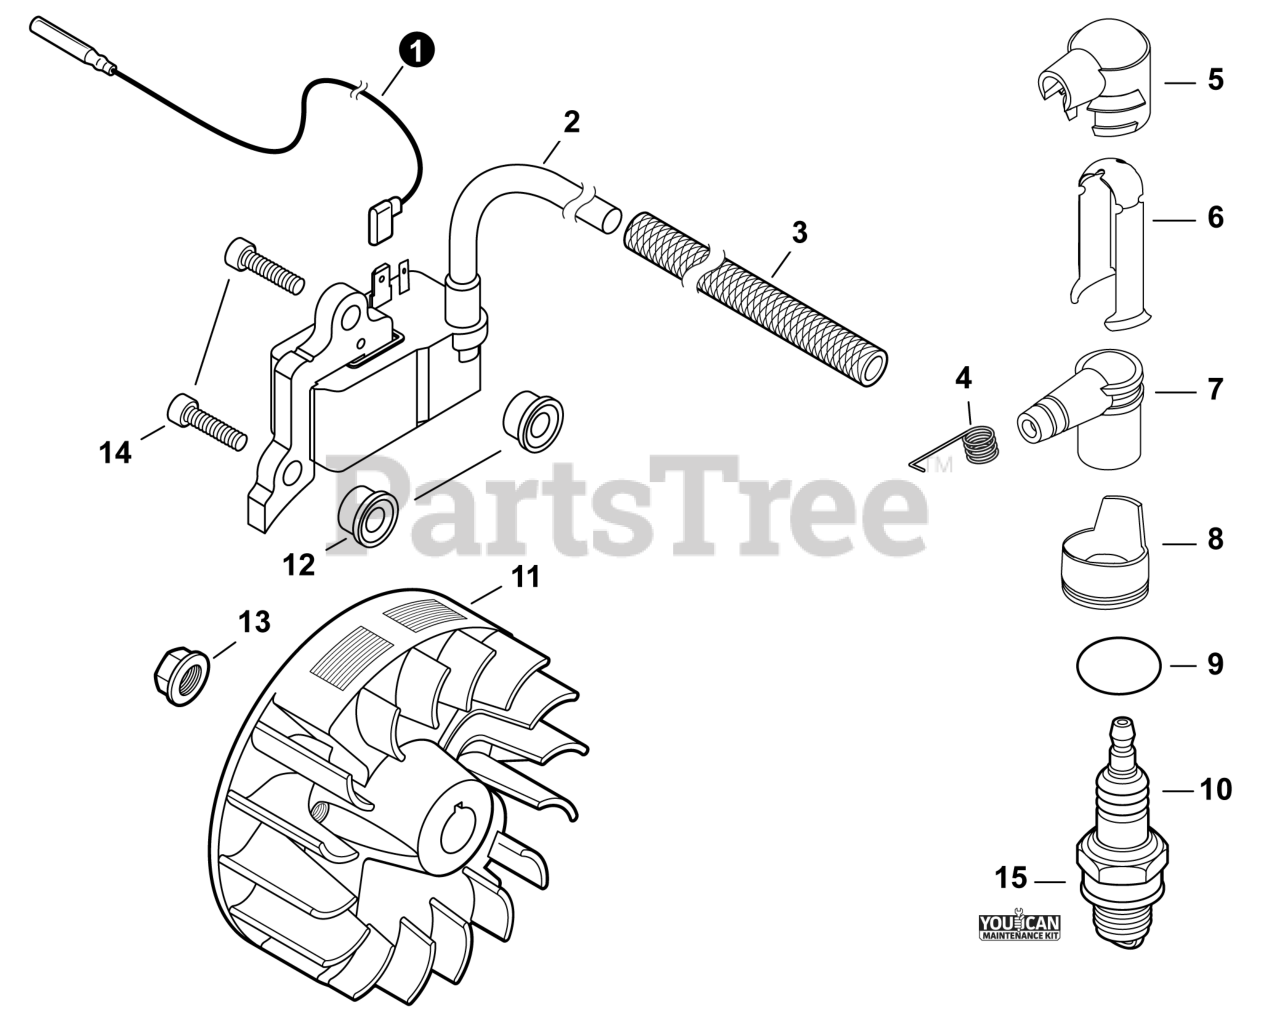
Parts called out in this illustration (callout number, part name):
2	COIL, IGNITION
3	TUBE, INSULATOR
4	TERMINAL, SPARK PLUG
5	COVER, CAP
6	SHIELD, SPARK PLUG
7	CAP, SPARK PLUG
8	PIECE, COVER
9	O-RING 22
10	SPARK PLUG - CMR7H
11	FLYWHEEL
12	WASHER 5
13	NUT, FLANGE M8
14	BOLT, TORX 5x20
15	TUNE-UP KIT - YOUCAN™
